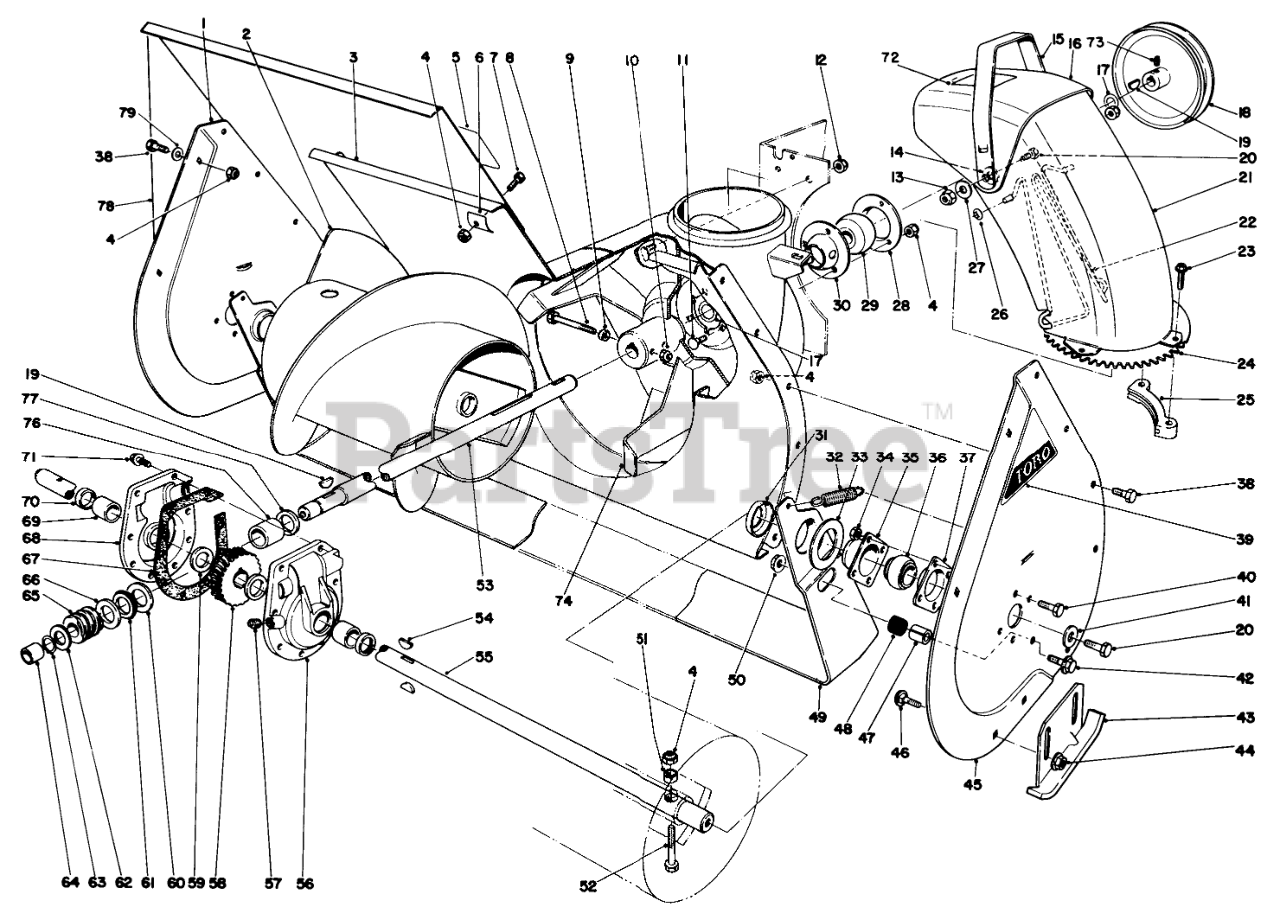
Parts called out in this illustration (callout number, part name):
1	RH AUGER SIDE PLT R
2	Auger Right
3	AUGER HSG WA RO
4	NUT-LOCK, NI
5	DECAL-WARNING, AUGER
6	SHIELD CLAMP R
7	SCREW-HH
8	SCREW-HHF
9	SPACER
10	NUT-LOCK, NI
11	BOLT-CARR
12	NUT-LOCK, NI
13	NUT-LOCK, CONE
14	WASHER-RUBBER
15	DEFLECTOR HANDLE B
16	DEFLECTOR/DECAL
17	WASHER
18	IMPELLER PULLEY
19	KEY-WOODRUFF
20	SCREW-CARR
21	CHUTE B
22	CHUTE WIRE
23	SPECIAL SCREW
24	Gear-Chute Swivel
25	CHUTE RETAINER
26	NUT-PUSH
27	WASHER-BELLEVILLE
28	BEARING ASSEMBLY
29	BEARING-BALL
30	BEARING ASSEMBLY
31	Positioner-Scraper
32	SPRING-TENSION
33	SCRAPER BLADE SPACER
34	NUT-LOCK, CONE
35	BEARING-FLANGE, FRONT
36	BEARING
37	BEARING-FLANGE, REAR
38	SCREW-HH
39	AUGER SIDE PLT DECAL
40	SCREW-HH
41	WASHER
42	SCREW-HHF
43	AUGER SKID WA R
44	NUT-HHF, WHIZ
45	LH AUGER SIDE PLT R
46	SCREW-CARR
47	SCRAPER STOP SPACER
48	SCRAPER STOP CUSHION
49	24 SCRAPER BLD
50	NUT-HF
51	SPACER-HUB, AUGER
52	Auger Bolt
53	IMPELLER SHAFT
54	KEY-WOODRUFF
55	24 AUGER SHAFT
56	Gear Case (Incl. Ref. #69 & 70)
57	PLUG-PIPE, SQH
58	GEAR-WORM, 27T
59	WASHER-THRUST
60	WASHER-THRUST
61	BEARING-THRUST
62	WASHER-THRUST
63	Ring-Snap
64	BUSHING
66	THRUST-WASHER
67	GASKET-CASE, GEAR
68	Gear Case (Incl. Ref. #69 & 70)
69	BUSHING
70	SEAL-OIL
71	SCREW-TAPTITE
72	Decal-Discharge
73	SCREW-SET, SQH
74	IMPELLER WA B
76	BUSHING-SPECIAL
77	RING-QUAD
78	AUGER EXT 24 SCND R
79	WASHER-PLAIN
